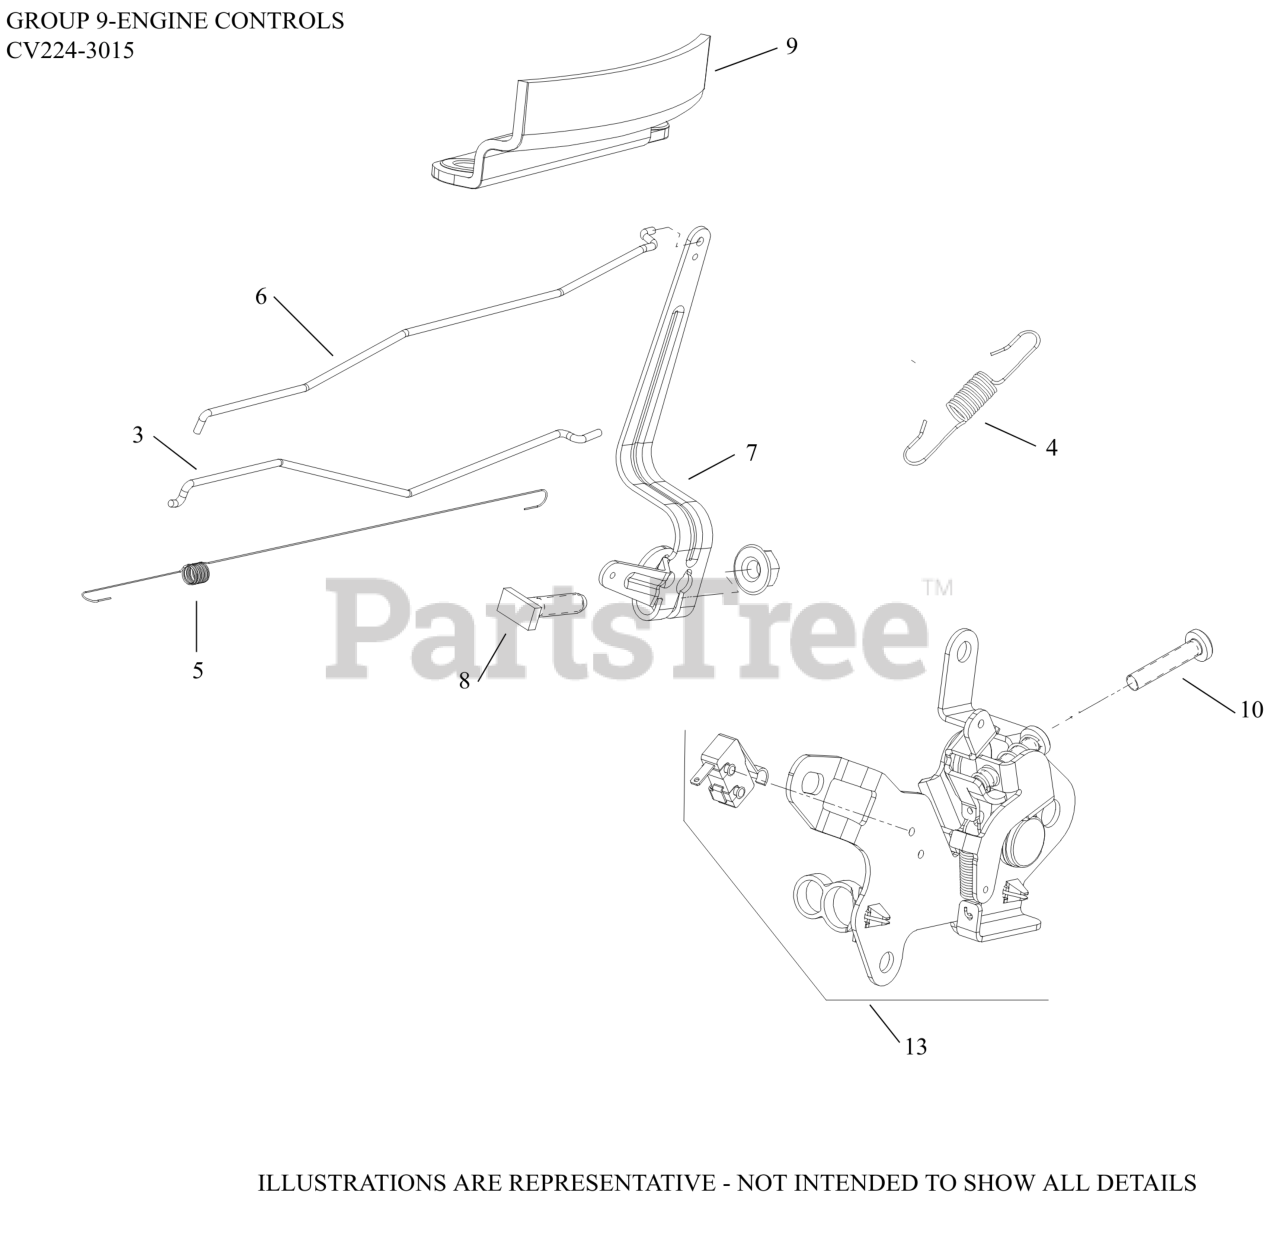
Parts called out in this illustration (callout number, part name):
3	LINKAGE, CHOKE
4	SPRING, GOVERNOR
5	SPRING, LINKAGE
6	LINKAGE, GOVERNOR
7	LEVER, GOVERNOR
8	SCREW, RECTANGLE HEAD (M6)
9	GUARD, FINGER
10	SCREW, SPEED ADJUSTING
13	CONTROL ASSEMBLY, REMOTE VARIABLE SPEED
13	SPEED CONTROL ASSEMBLY
